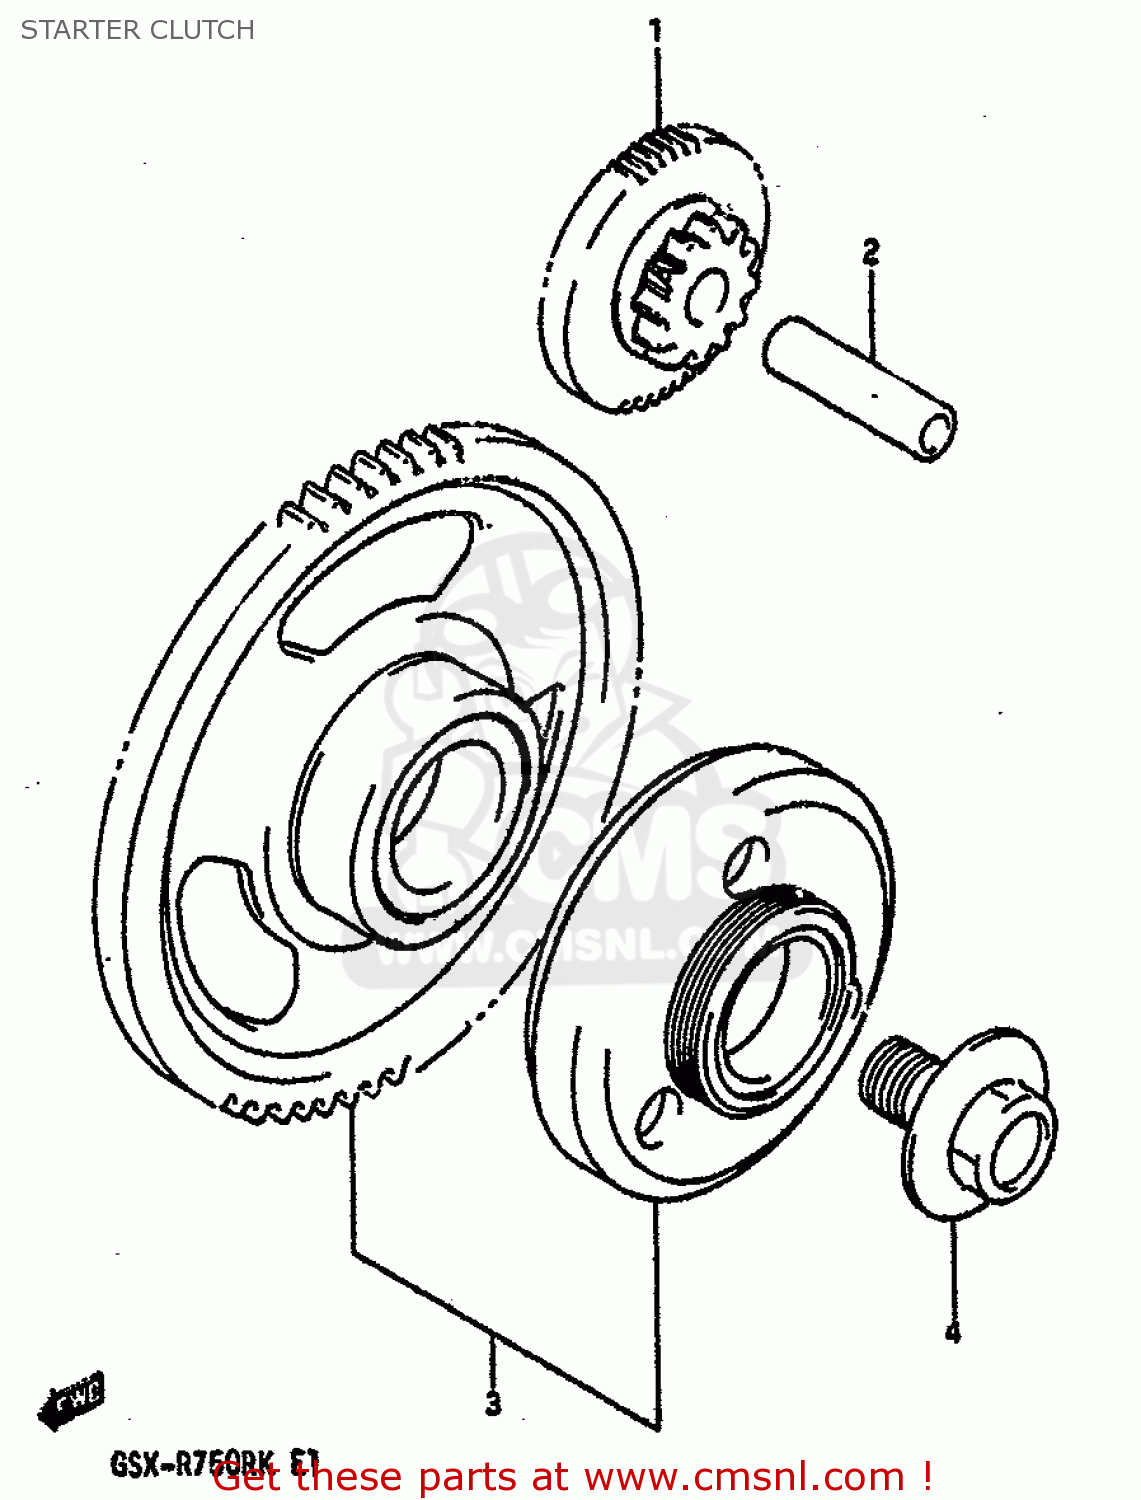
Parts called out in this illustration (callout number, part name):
1	GEAR,STARTER IDLE
2	PIN(7X11X42)
3	CLUTCH SET,STARTER
4	BOLT
